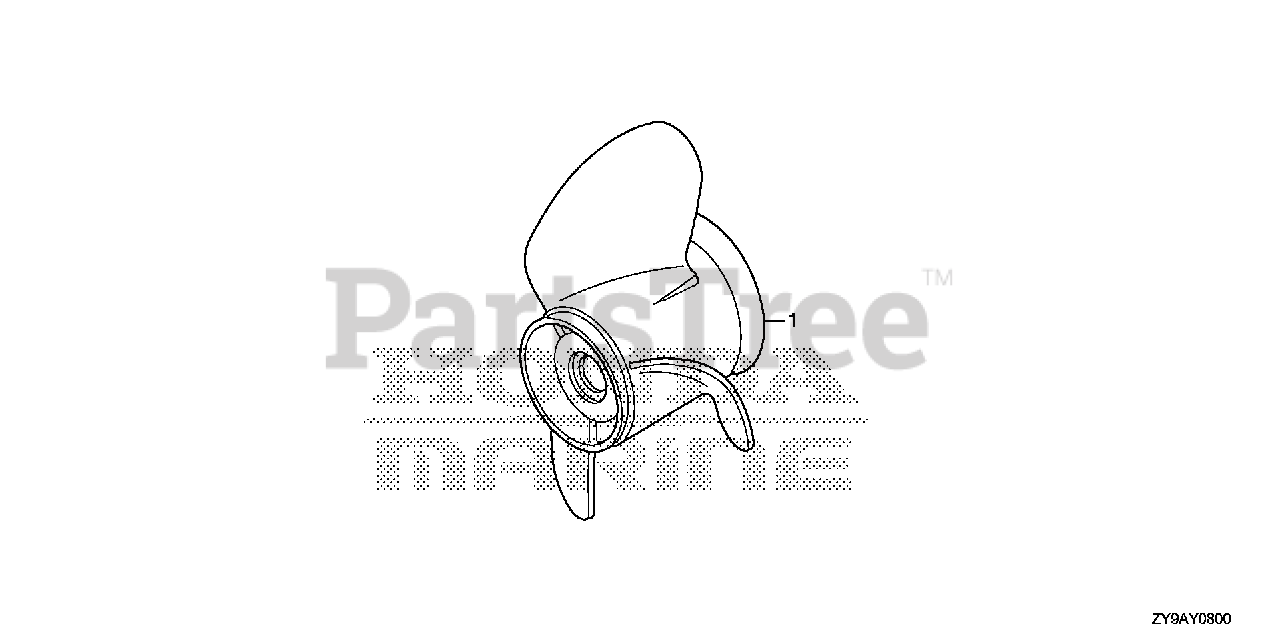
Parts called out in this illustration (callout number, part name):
1	PROPELLER, THREE-BLADE (13X19) (SUS) Use from Frame SN 1302132.
1	PROPELLER, THREE-BLADE (13X21) (SUS) Use from Frame SN 1302132.
1	PROPELLER, THREE-BLADE (14X11) *NH283* (AL) Use from Frame SN 1302160.
1	PROPELLER, THREE-BLADE (13-3/4X13) *NH283* (AL) Use from Frame SN 1302160.
1	PROPELLER, THREE-BLADE (13-1/2X15) *NH283* (AL) (STIN GRAY)
1	PROPELLER, THREE-BLADE (13-1/4X17) *NH283* (AL) Use from Frame SN 1302160.
1	PROPELLER, THREE-BLADE (13X21) *NH283* (AL) Use from Frame SN 1302160.
1	PROPELLER, THREE-BLADE (13X19) *NH283* (AL) (STIN GRAY)
1	PROPELLER, THREE-BLADE (13-1/4X17) (SUS) Use from Frame SN 1302160.
1	PROPELLER, THREE-BLADE (13-1/4X15) (SUS/HAC)
1	PROPELLER, THREE-BLADE (13-1/4X17) (SUS/HAC)
1	PROPELLER, THREE-BLADE (13-1/4X19) (SUS/HAC)
1	PROPELLER, THREE-BLADE (13-1/4X21) (SUS/HAC)
1	PROPELLER, THREE-BLADE (13-1/5X19) *NH283* (STIN GRAY)
1	PROPELLER, THREE-BLADE (13-1/5X21) *NH283* (STIN GRAY)
